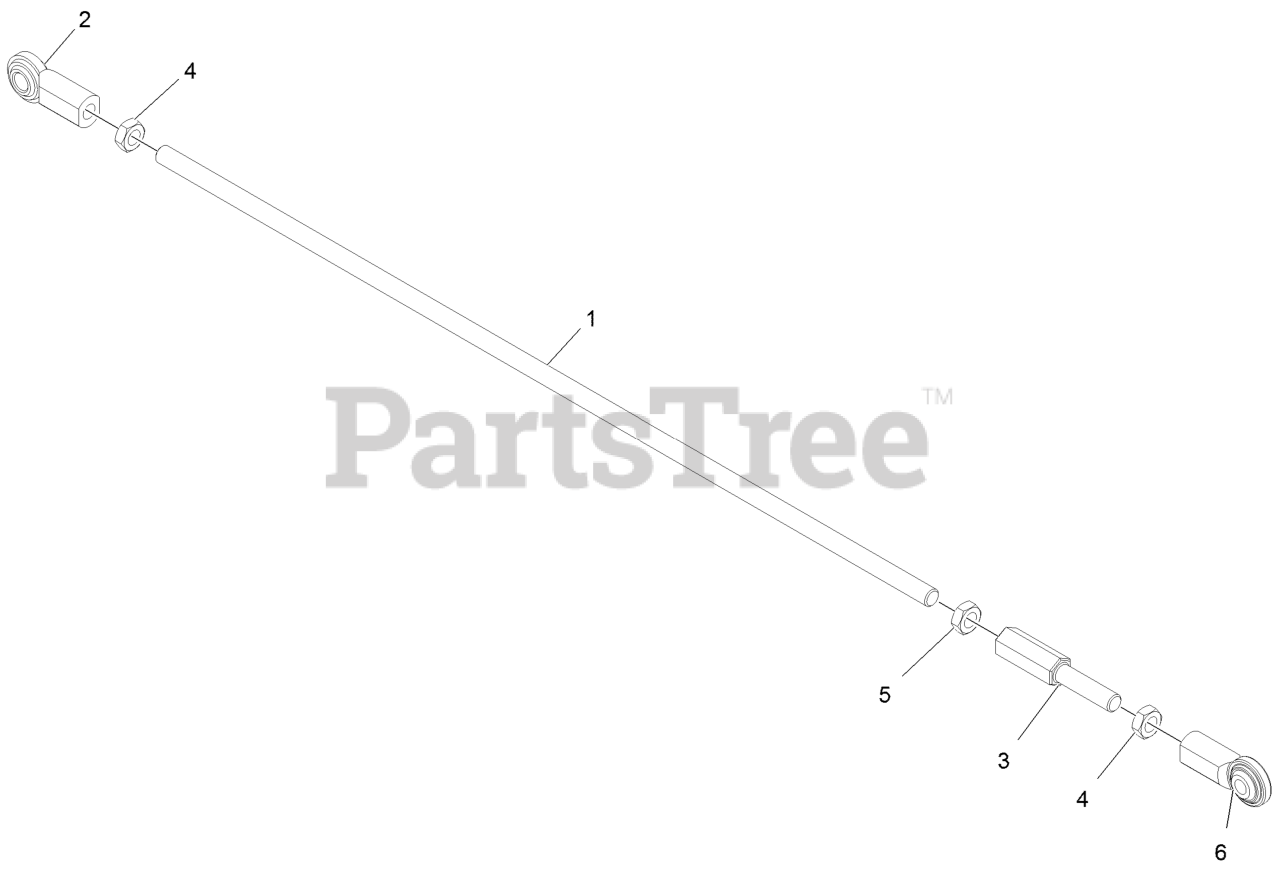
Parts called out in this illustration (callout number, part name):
1	LINKAGE, MOTION
2	JOINT-BALL, END
3	ROD-ADJUSTMENT
4	NUT-HJ
5	NUT-HEX JAM, LH
6	JOINT-BALL, END
